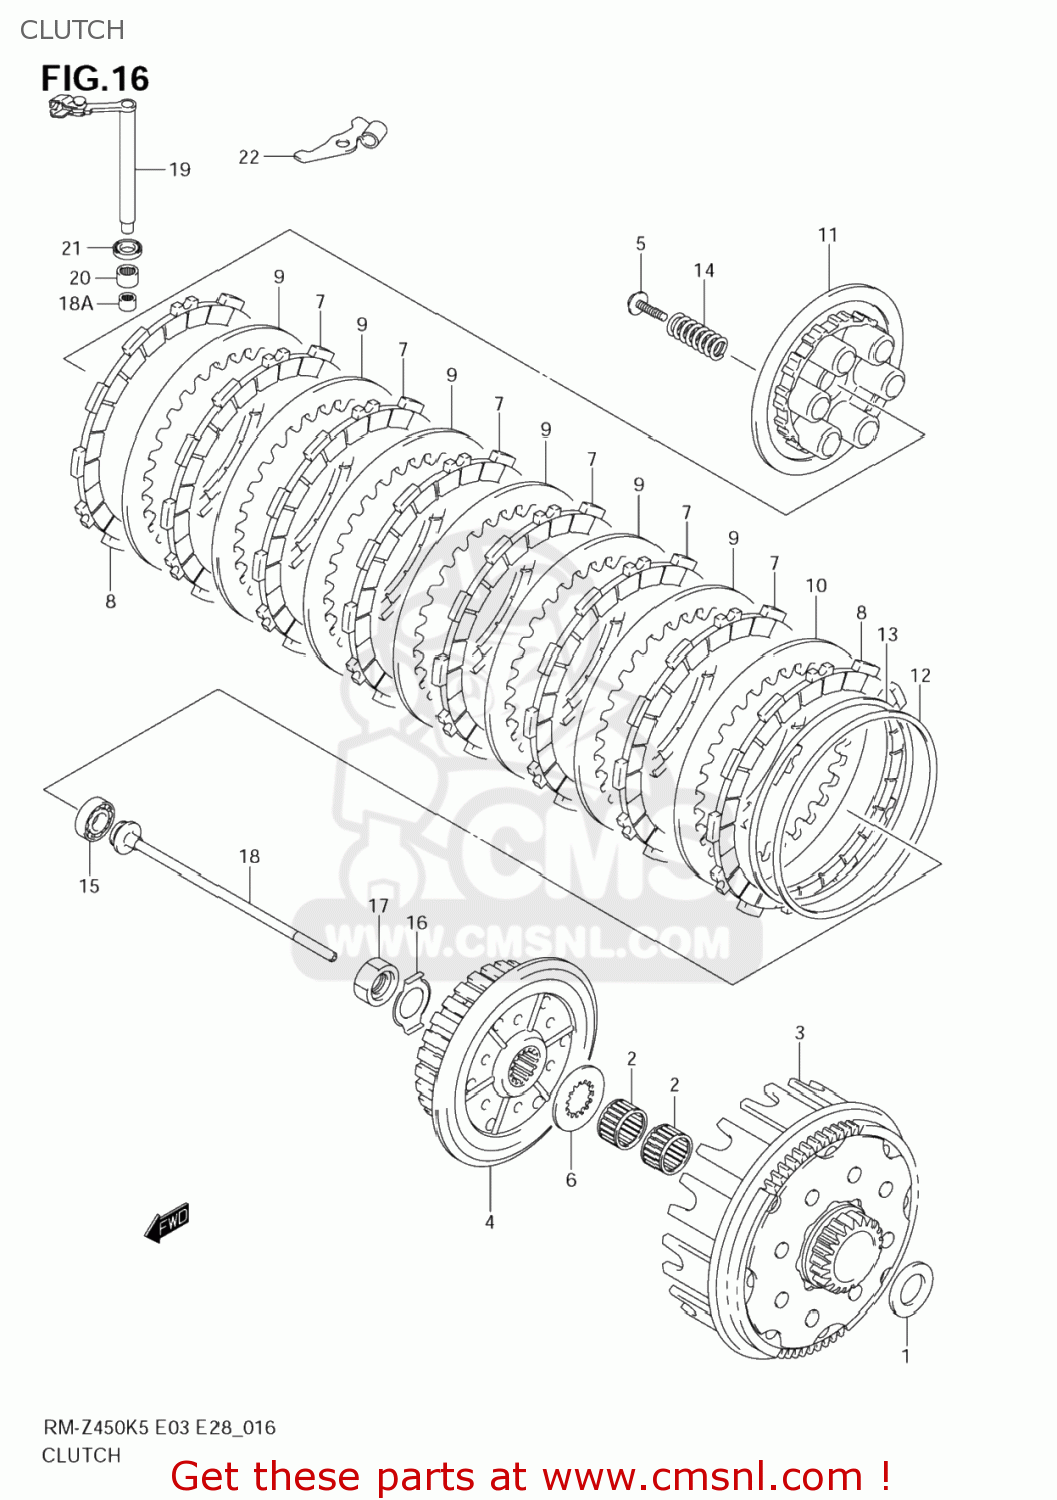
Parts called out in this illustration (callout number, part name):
1	SHIM(25X34X1.3)
2	BEARING(25X29X13)
3	GEAR ASSY,PRI DRIVEN
4	HUB,CLUTCH SLE
5	BOLT,CLUTCH SPRING(6X25)
6	WASHER,CLUTCH SLEEVE(19.5X45X3
7	PLATE,CLUTCH DRIVEN NO.1 (NAS)
8	PLATE,CLUTCH DRIVE NO.2 (NAS)
9	PLATE,CLUTCH DRIVEN (NAS)
10	PLATE,CLUTCH DRIVEN (NAS)
11	DISC,CLUTCH PRESSURE
12	SEAT,WAVE WASHER
13	WASHER,CLUTCH PLATE WAVE
14	SPRING
15	BEARING
16	WASHER,CLUTCH
17	NUT
18	ROD,CLUTCH PUSH
18A	BEARING,CLUTCH RELEASE(7X11X9)
19	CAMSHAFT,CLUTCH RELEASE
20	BEARING(10X14X10)
21	SEAL,OIL(10X17X5)
22	BRACKET,CLUTCH CABLE
